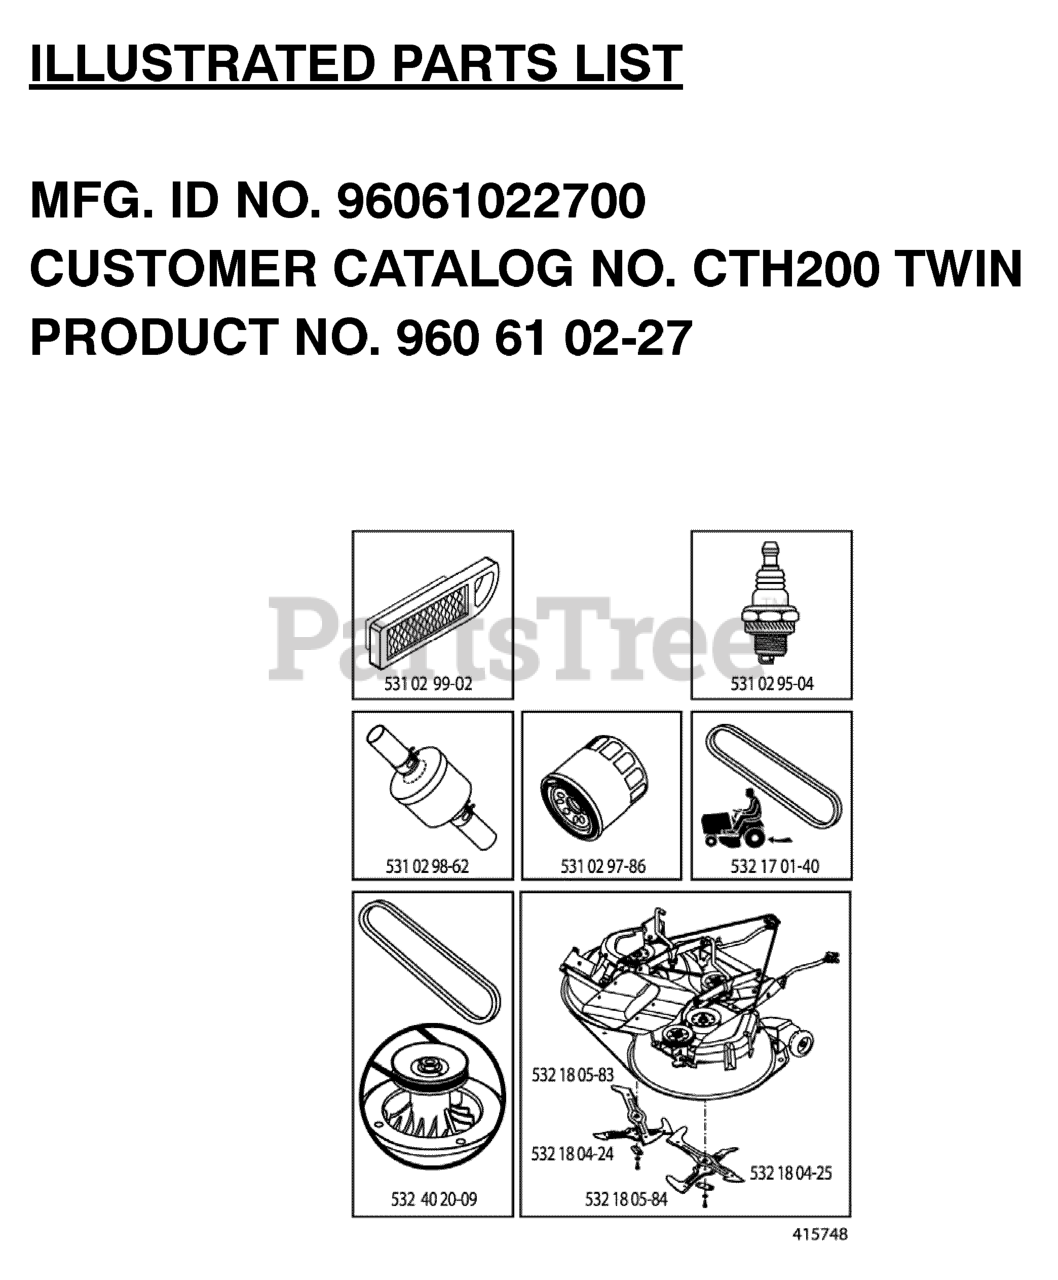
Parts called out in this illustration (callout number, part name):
1	SEAT - GREY
2	BRKT.PIVOT.FENDER
3	STRAP
6	NUT
7	SPRING COMPRESSION
8	BOLT.5/16-18UNCX3/4 W/SEMS.BLK
10	PAN.ASM.SEAT.3PT
21	BOLT.SHOULDER.5/16-18
37	NUT.71038.31-18.HEX.NYLOCK
40	HANDLE.SLIDE.SEAT.TEX.BLACK
41	SPRING.LATCH.SEAT.TEX
44	WASHER 13/32 X 2-3/8 X 12GA
